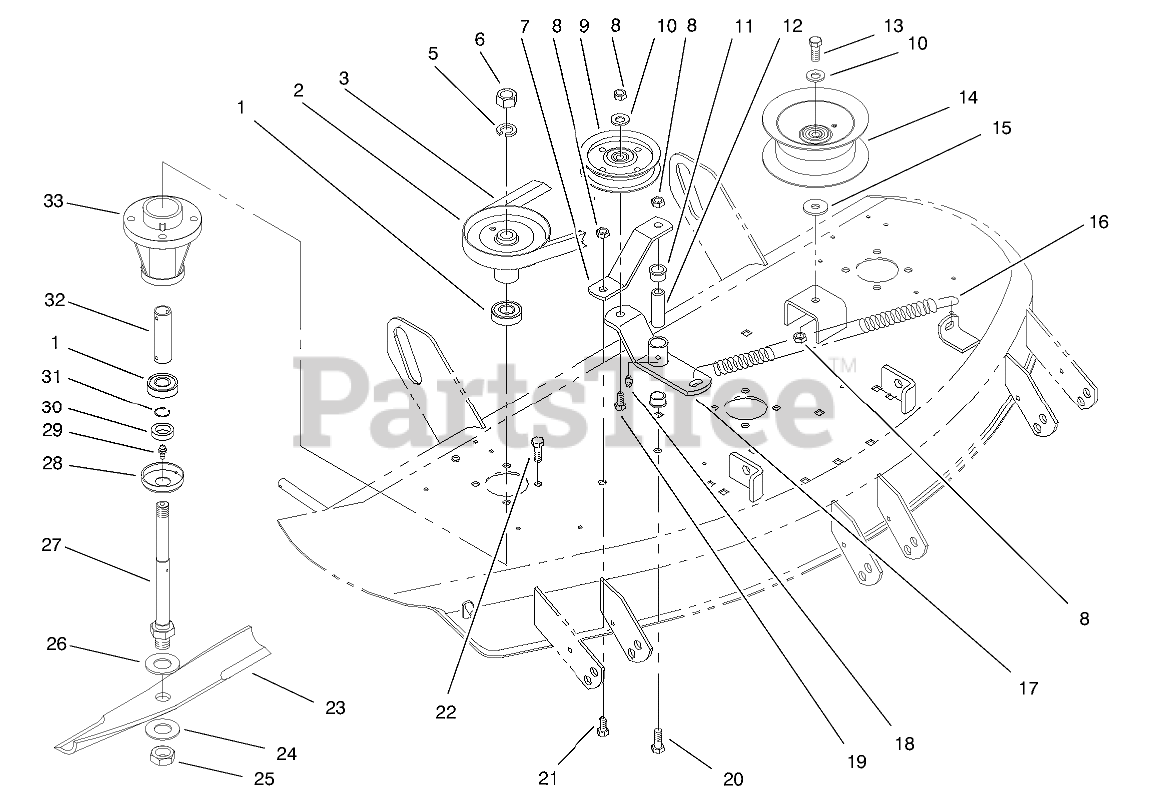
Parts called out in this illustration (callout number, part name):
1	BEARING-BALL
2	PULLEY
3	V-BELT
5	WASHER-LOCK
6	NUT-JAM
7	Strap-Brace
8	NUT-LOCK, NI
9	PULLEY-IDLER, FLAT
10	WASHER-FLAT
11	BUSHING
12	SPACER
13	SCREW-HH
14	PULLEY-IDLER
15	WASHER
16	SPRING - EXTENSION
17	Arm-Idler
18	FITTING-GREASE
19	SCREW-HH
20	SCREW-HH
21	SCREW-HH
22	SCREW-HH
23	14IN BLADE KIT
24	WASHER-FLAT
25	NUT-JAM
26	WASHER-FLAT
27	SHAFT-SPINDLE
28	CUP-SPINDLE
29	FITTING-GREASE
30	SPACER-BLADE
31	RING-RETAINING
33	HOUSING-SPINDLE
